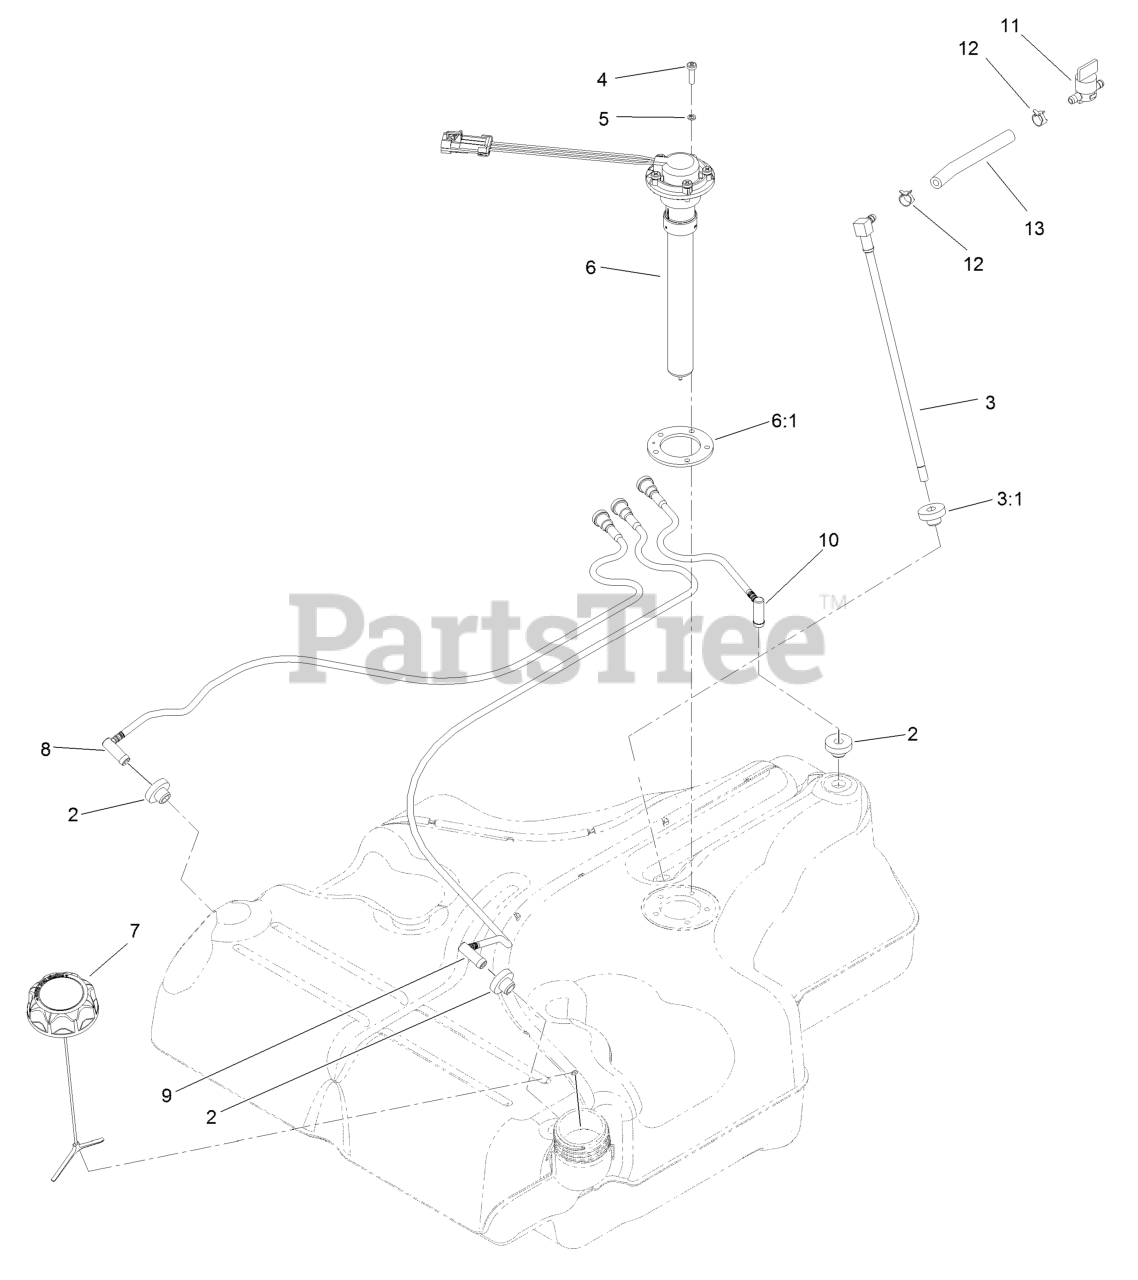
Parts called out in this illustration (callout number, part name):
2	SHEAVE
3	CLUTCH KIT
4	WASHER-CLUTCH
5	WASHER-SPRING
6	SCREW-HH 7/16-20 X 1 1/2 W/LOCTITE
7	SCREW-CARR
8	SCREW-HH
9	ENGINE OIL DRAIN HOSE ASM
9:1	PLUG-HH
9:1:1	O-RING
10	WASHER-BELLEVILLE
12	CLUTCH-ANCHOR
13	SCREW-HH
14	NUT-HF, NI
15	WASHER-SPRING
17	SCREW-HHF
18	MUFFLER
19	BRACKET-MUFFLER
20	HOSE-FUEL
21	CLAMP-HOSE
22	SCREW-HHF
